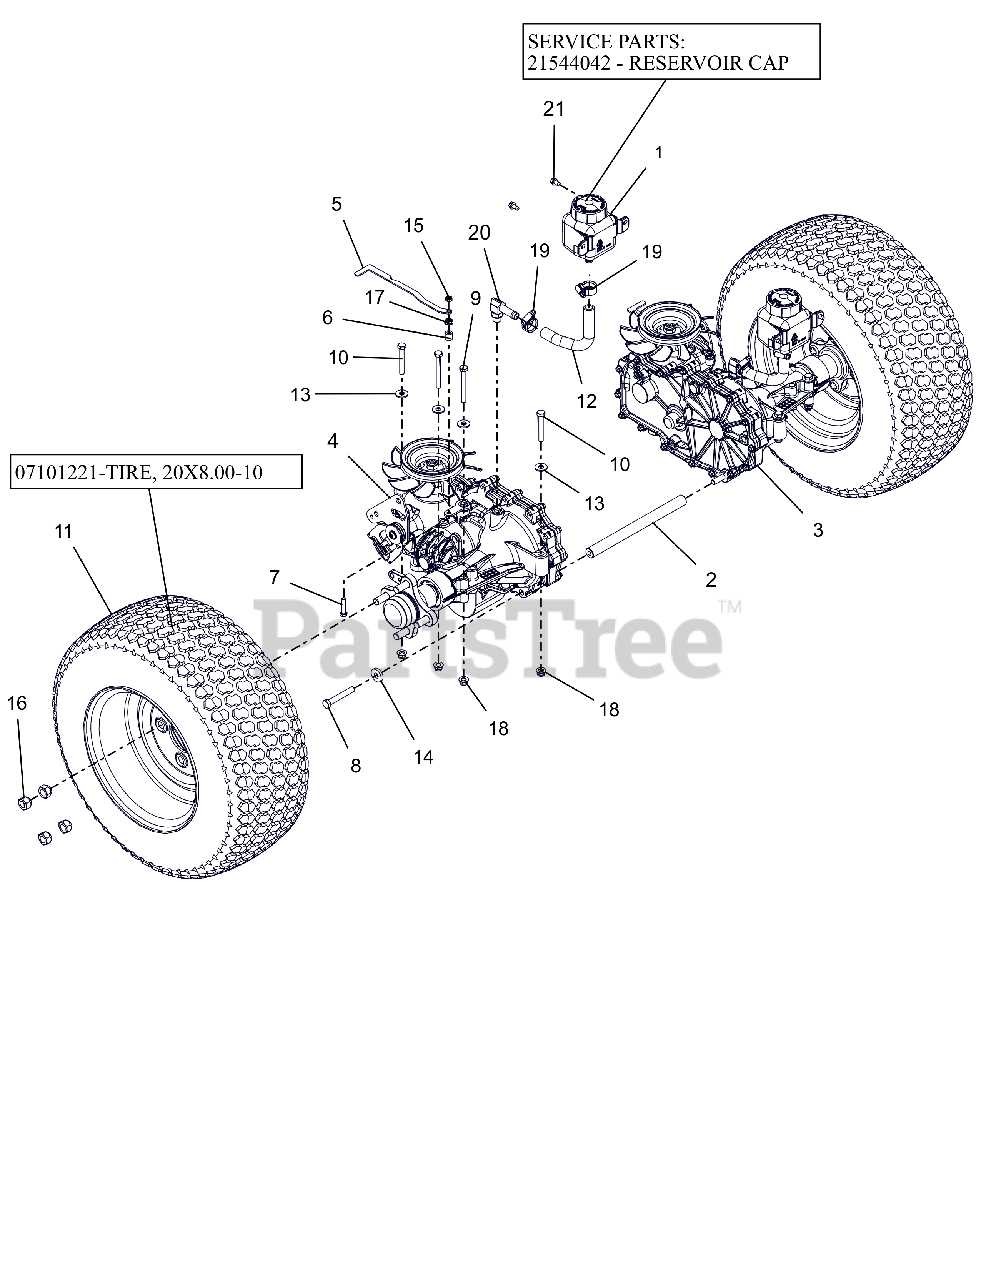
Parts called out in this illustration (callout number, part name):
1	TANK, EXPANSION
1	CAP, HYDRO RESERVOIR REPLAC.
2	ROD, TRANSAXLE BRACE (LONG)
3	TRANSAXLE,ZT2800 LH
4	TRANSAXLE,ZT2800 RH
5	BRKT, DUMP VALVE
6	BSHG-SLV .265X.500X.500
7	@BLT-HEX .25-20X1.25 GR5 YWZC
8	@BLT-HEX .38-16X2.50 GR5 YWZC
9	@BLT-HEX .31-18X2.75 GR5 YWZC
10	@BLT-HEX .31-18X2.25 GR5 YWZC
11	ASM, WHL/TIRE 20X8.00-10
11	TIRE, 20X8.00-10
11	TUBE, 20X10-10
12	HOSE, FORMED LH XL
13	@WSHR-FL-STL.38X.875X.083 YWZC
14	WSHR-FL-STL .406X1.00X.188 YWZ
15	NUT-LK-CTR JAM .25-20 YWZC
16	WHEEL NUT .500-20 YZ
17	@NUT-SPNLK-FLG .25-20 YWZC
18	@NUT-LK-NYL-FLG .31-18 YWZC
19	CLAMP,.88 DIA. HOSE
20	FITTING, HYD (90 DEG)
21	SCR-TAP .25-20X.50 HWH TR YWZ
